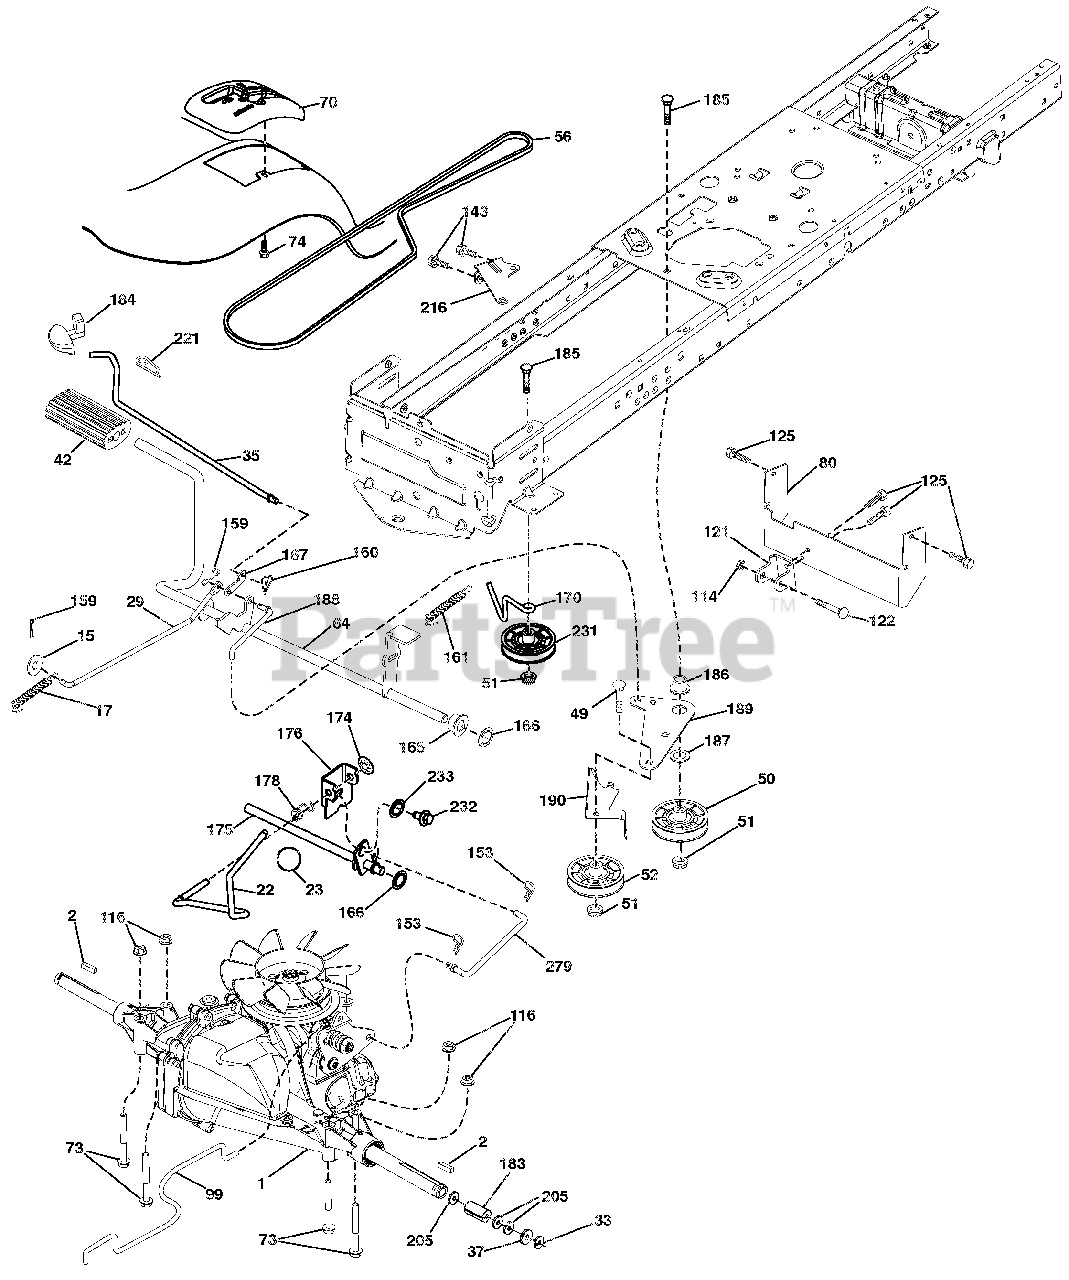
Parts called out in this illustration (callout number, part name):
2	KEY.SQUARE.2.0 X .1845/.1865
15	WASHER.13/32 X 13/16 X 16 GA.
22	ROD.SHIFT.FENDER.TLT.2006
23	KNOB DELUXE
29	ROD.BRAKE.T2.TEX
33	E-RING.#5133-75
35	ROD.BRAKE.PARKING.LT.TEX
37	WASHER.25/32 X 1 1/4 X 16 GA.
42	COVER.PEDAL.BLK.ROUND
49	BOLT.RDHD.3/8-16UNCX1-3/4.GR5
50	IDLER.FLAT.910"OFFSET
51	Nut, Hex, Flangelock 3/8-16
52	IDLER.V-GROOVE.910"OFFSET
56	V-BELT.GROUND DRIVE.90.00
64	SHAFT ASM.PEDAL.BRAKE CONTROL
70	CONSOLE.SHIFT.STL.HYD.BLACK.TX
73	BOLT.HEX.FLGHD.5/16-18.GR.5
74	SCREW.HEX.WSH.HI-LO.1/4X1/2UNC
80	STRAP.TORQUE.FS.T2
99	ROD.ASM.BYPASS.SPRING.T2.FS
114	Locknut, Washer Insert 5/16-18
116	Nut, Lock Hex Flange 5/16-18 u
121	BRACKET.STRAP.TORQUE.T/A.3500
122	BOLT.5/16-18 x 2.50
125	SCREW.5/16-18X3/4.SMGML.TAP/BL
143	SCREW.THDROL.5/16-18 X 1/2TYTT
153	Retainer Spring
159	PIN.COTTER.1/8 X 3/4.CAD.
160	RETAINER.CLIP(M).DIA.290
161	SPRING.RETURN.CLUTCH.6.75
165	BUSHING.SHAFT.BRAKE.HAND CONTR
166	NUT.PUSH..625.2006
167	LATCH.BRAKE.PARKING
170	KEEPER.CENTER SPAN.1.688
174	NUT.PUSH..500
175	SHAFT ASM.SHIFT.T2/K66.FS.TX
176	ARM.CLEVIS.ROD.SHIFT
178	SPRING.SHIFT.GT.2006
183	SPACER.AXLE.PVST
184	HANDLE.PARKING BRAKE.LTTEX.505
185	BOLT.RDHD.3/8-16UNC X2-3/4 GR5
186	SPACER.RETAINER
187	WASHER.13/32 X 2 X 10 GA.
188	LINK.CLUTCH.GROUND DRIVE
189	BELLCRANK.GROUNDRIVE.NSTG/NSTL
190	KEEPER.BELLCRANK.DRIVE.GROUND
205	WASHER.25/32 X 1-5/8 X 16GA.
216	BRACKET.PULLEY.IDLER.WTEX
221	RETAINER.SPRING.CLIP.HANDLE
231	IDLER.V-GROOVE.1.688"OFFSET
232	BOLT.FIN HEX.7/16-14X1 GR5
233	WASHER.SERRATED
279	LINK.SHIFT.T2.TEX
